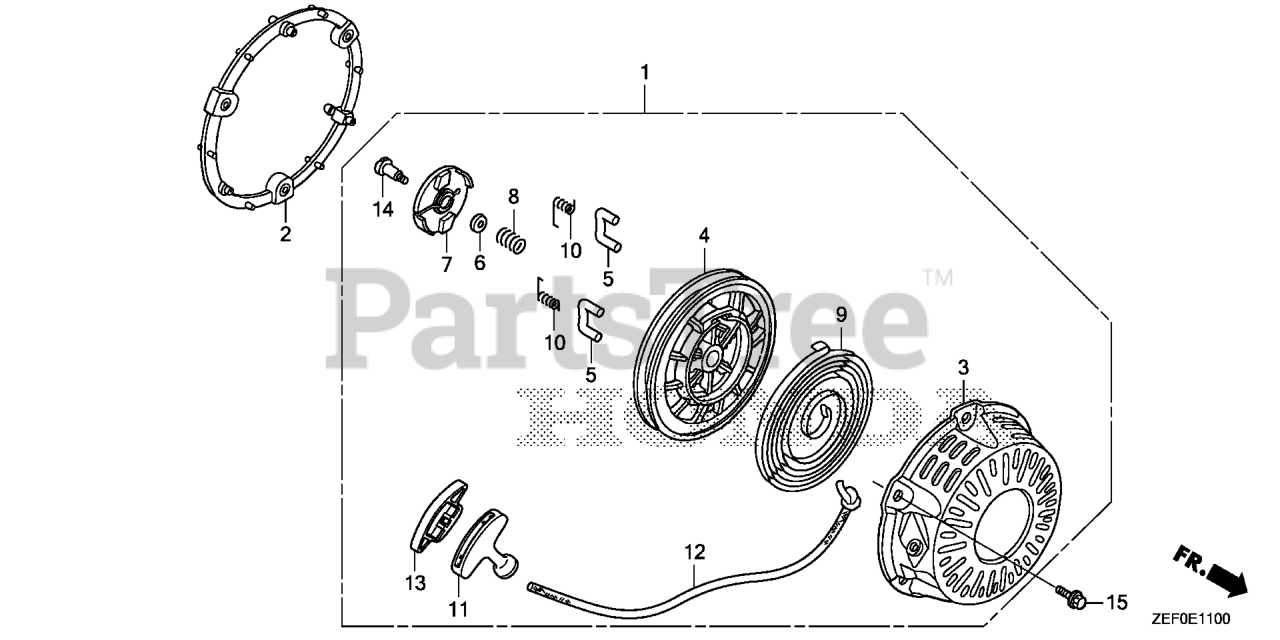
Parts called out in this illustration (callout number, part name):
1	STARTER ASSY., RECOIL *R280* (COO)(FOR U.S.A.) (POWER RED)
2	SPACER, RECOIL STARTER MOUNTING *R280* (POWER RED)
3	CASE, RECOIL STARTER *R280* (POWER RED)
4	REEL, RECOIL STARTER (BLACK)
5	RATCHET, STARTER
6	PLATE, FRICTION
7	GUIDE, RATCHET
8	SPRING, FRICTION
9	SPRING, RECOIL STARTER
10	SPRING, RETURN
11	KNOB, RECOIL STARTER
12	ROPE, RECOIL STARTER (#5X55")
13	KNOB, REINFORCEMENT
14	SCREW, SETTING
15	BOLT, FLANGE (6X18)
